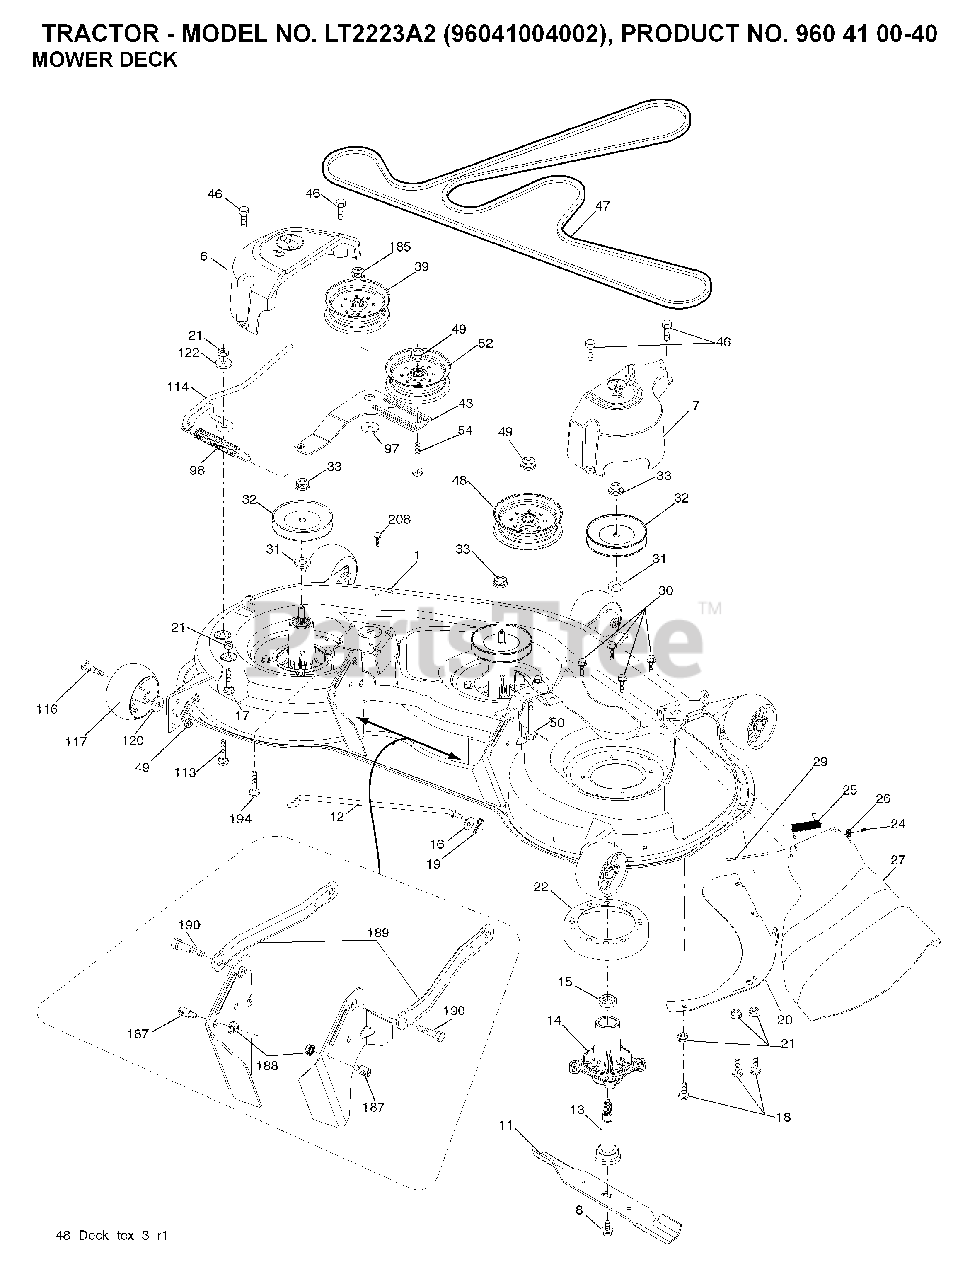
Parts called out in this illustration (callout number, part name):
1	DECK.WELDMENT.48"2006
6	COVER.MANDREL.LH.48"
7	COVER.MANDREL.RH.48"
8	BOLT 7/16 ASM BLADE
11	48" HI-LIFT BLADE
12	ROD.ANTI.SWAY.48/54"K4
13	SHAFT ASM MANDREL
14	HOUSING MANDREL
16	WASHER
17	BOLT
18	BOLT
19	PIN.COTTER.5/16.BOW TI
20	BAFFLE, VORTEX MWR
21	LOCKNUT
22	STRIPPER, MWR ROUND
24	CAP-SLEEVE LT
25	SPRING, TORSION
26	NUT PUSH M
27	DEFLECTOR SUBS TO 532 180655
29	ROD.HINGE
30	SCREW, WASHER HEAD
31	WASHER.SPACER.MANDREL
32	PULLEY MANDREL
33	NUT.FLANGE.LOCK.TOP
39	PULLEY.IDLER.4.50/HUB SPECIAL
43	ARM.IDLER
46	SCREW.1/4-20X5/8
47	BELT.DRIVE.DECK
48	PULLEY.IDLER.48"PRIMARY
49	NUT LOCK FLG 3/8-16 UNC
50	SCREW TT 3/8-16X2-1/4 UNC
52	PULLEY.IDLER.2006
54	BOLT.3/8-16X1.50
98	SPRING, DECK DRIVE
114	ROD.TENSION.RELIEF.TEX
116	BOLT.SHOULDER.3/8-16X3-5/8
117	WHEEL. GUAGE RALLY
122	BUSHING.RELIEF.TENSION
185	NUT.LOCK.FLANGE.7/16
187	STUD.FASTNER.W/ANTI-ROTATE
188	NUT LOCK HEX FLANGE 5/16-18
189	ARM.SUSPENSION.MOWER
190	BOLT.SHOULDER
194	BOLT.CARR.SQNK.7/16
208	SCREW 3/8-16X1/2
